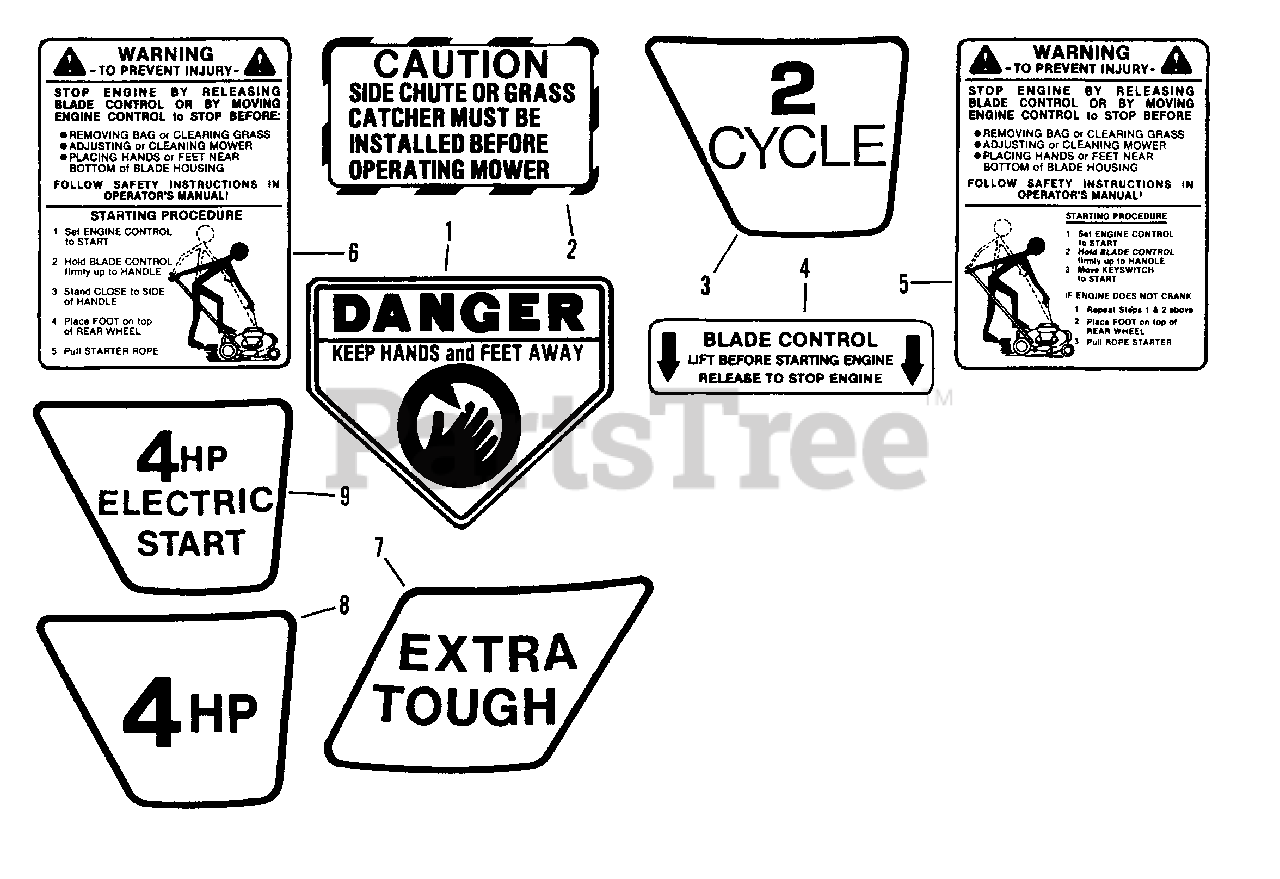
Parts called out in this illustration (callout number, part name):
1	DECAL, Danger
2	DECAL, Caution
4	DECAL, Blade Control
5	DECAL, Electric Start
6	DECAL, Manual Start
7	DECAL, Extra Tough
8	DECAL, 4 H.P.
9	DECAL, 4 H.P. Electric Start
